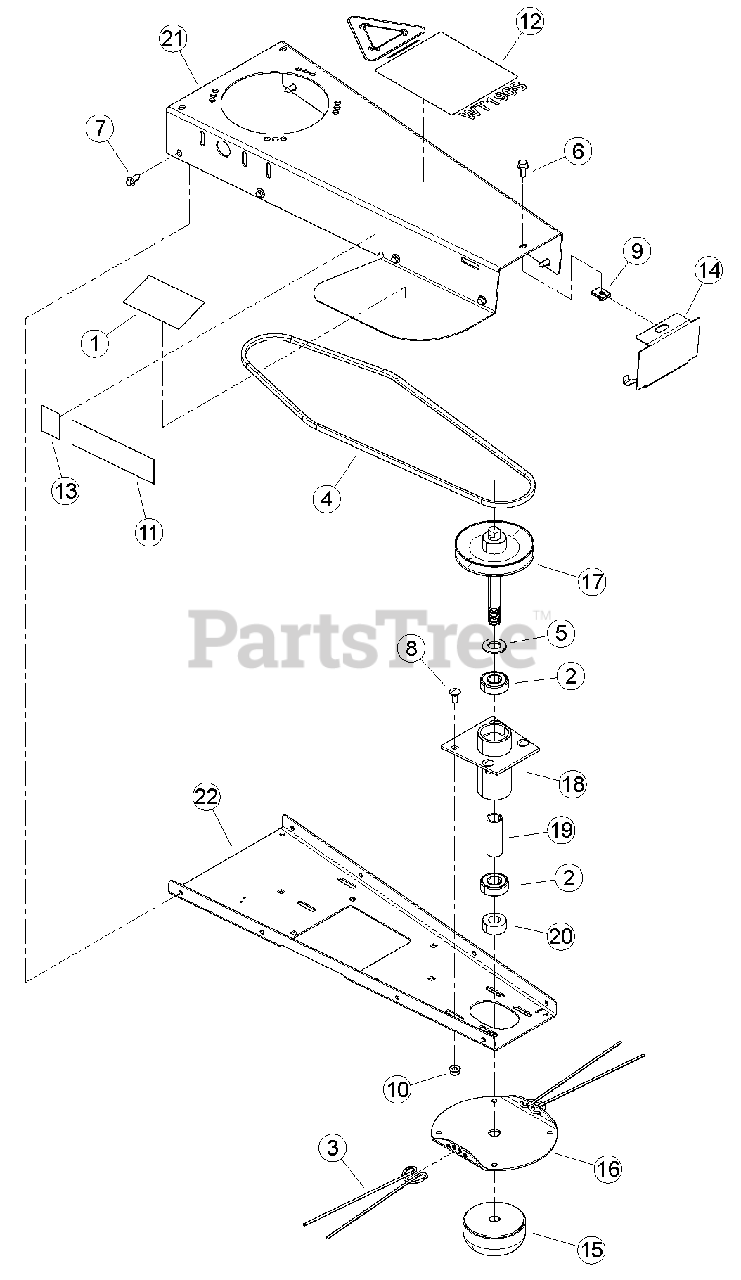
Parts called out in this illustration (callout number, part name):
1	DECAL, GRINDER DANGER
2	BEARING, 3/4 BALL
3	STRING, .155 X 20-1/2
4	BELT, 3LX52
5	WASHER, 3/4" SAE FLAT ZP
6	BOLT, 5/16 X 3/4 FLANGE NC
7	SCREW, 11/32-12 X 7/8 HWH T-AB
8	BOLT, 5/16 X 3/4 GR5 NC CRG ZP
9	NUT, 5/16"-18 TINNERMAN U-TYPE
10	NUT, 5/16-18 NYLOCK-FLANGE
11	DECAL, ECHO BEARCAT 6.82 X 1.90
12	DECAL, WT190S INFORMATION
13	DECAL, ECHO BEARCAT QR CODE
14	COVER, FRONT TRIMMER
15	WELDMENT, TRIMMER HEAD (HEAT TREAT)
16	DISK, TRIMMER HEAD
17	WELDMENT, TRIMMER PULLEY
18	WELDMENT, SPINDLE HUB
19	SPACER, TRIMMER SPINDLE
20	SPACER, TRIMMER HEAD
21	BODY, TRIMMER
22	BOTTOM, TRIMMER FRAME
